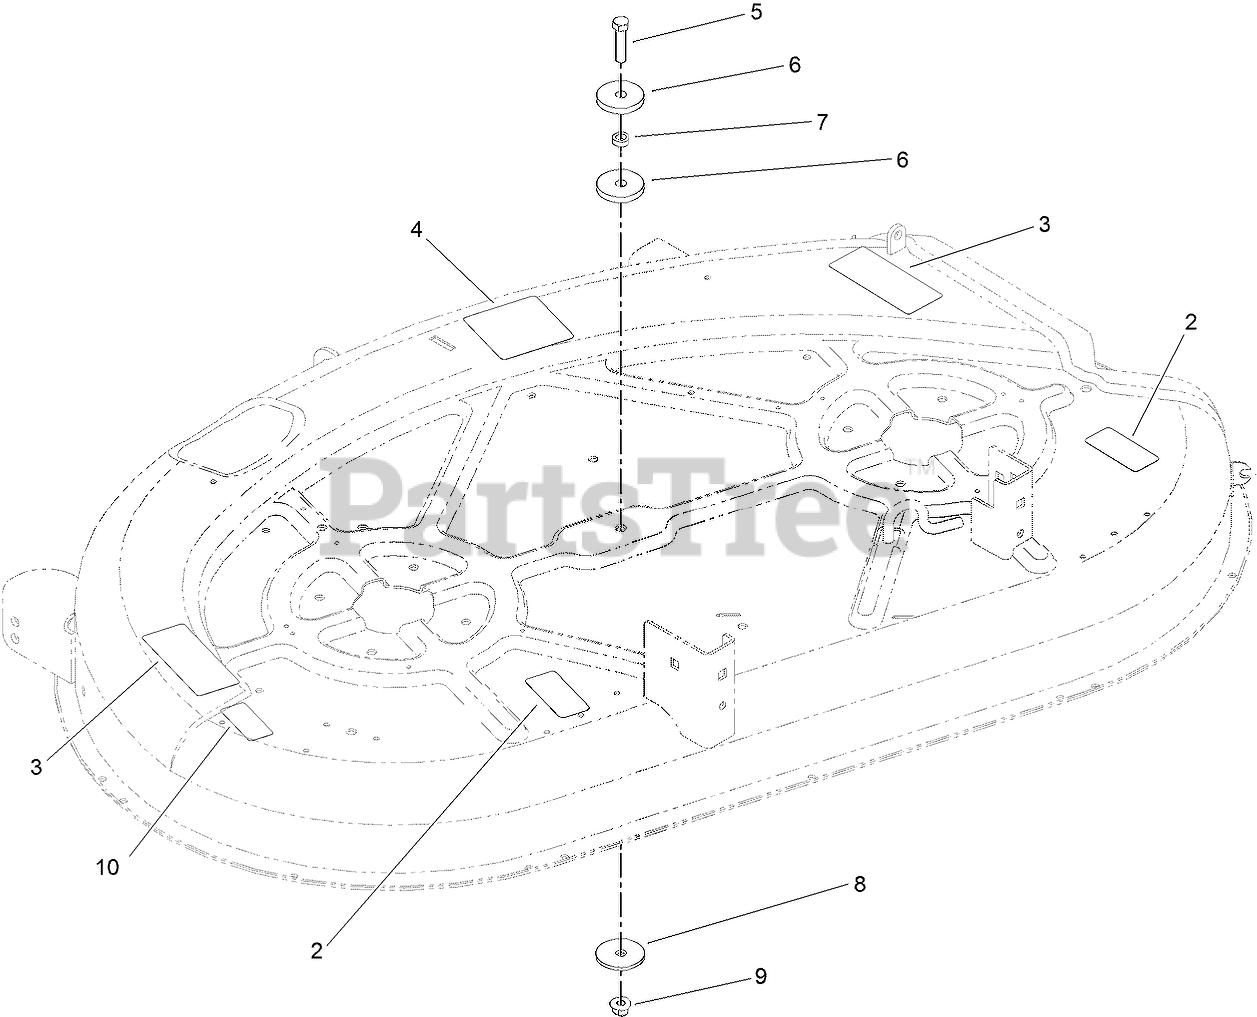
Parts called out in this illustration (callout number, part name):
2	DECAL-WARNING
3	DECAL-WARNING
4	DECAL-GUIDE, BELT
5	SCREW-HH
6	WASHER-PLAIN
7	SPACER
8	WASHER-REBOUND
9	NUT-HF, NI
10	DECAL-SERVICE DECK
